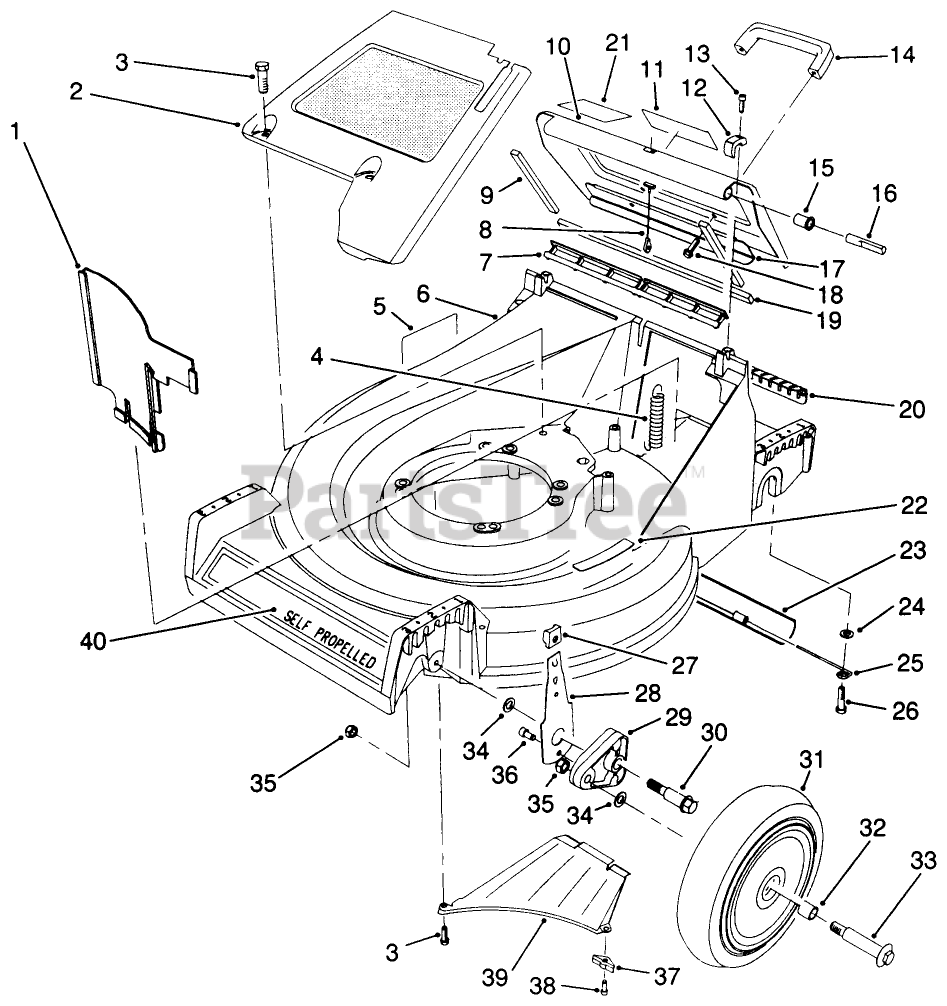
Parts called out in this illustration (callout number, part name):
1	PANEL-VERTICAL
3	SCREW-HWHTF
4	SPRING-EXTENSION
8	DOOR CABLE
13	SCREW-HSH
14	HANDLE-DOOR
15	DOOR BUSHING
18	SCREW-HWH
19	DOOR END SEAL
20	ACCESS COVER
22	DECAL - STEP PAD INT'L
23	TRAILING SHIELD
24	WASHER-PLAIN
25	SHIELD HANGER
26	SCREW-SHOULDER
27	KNOB-ARM
28	FRONT SPRING ARM ASM
29	ARM-PIVOT, FRONT
30	BOLT-SHOULDER
32	BUSHING
33	WHEEL BOLT
34	WASHER
36	SCREW-HSH, THREAD FORMING
38	SCREW-HWHTF
